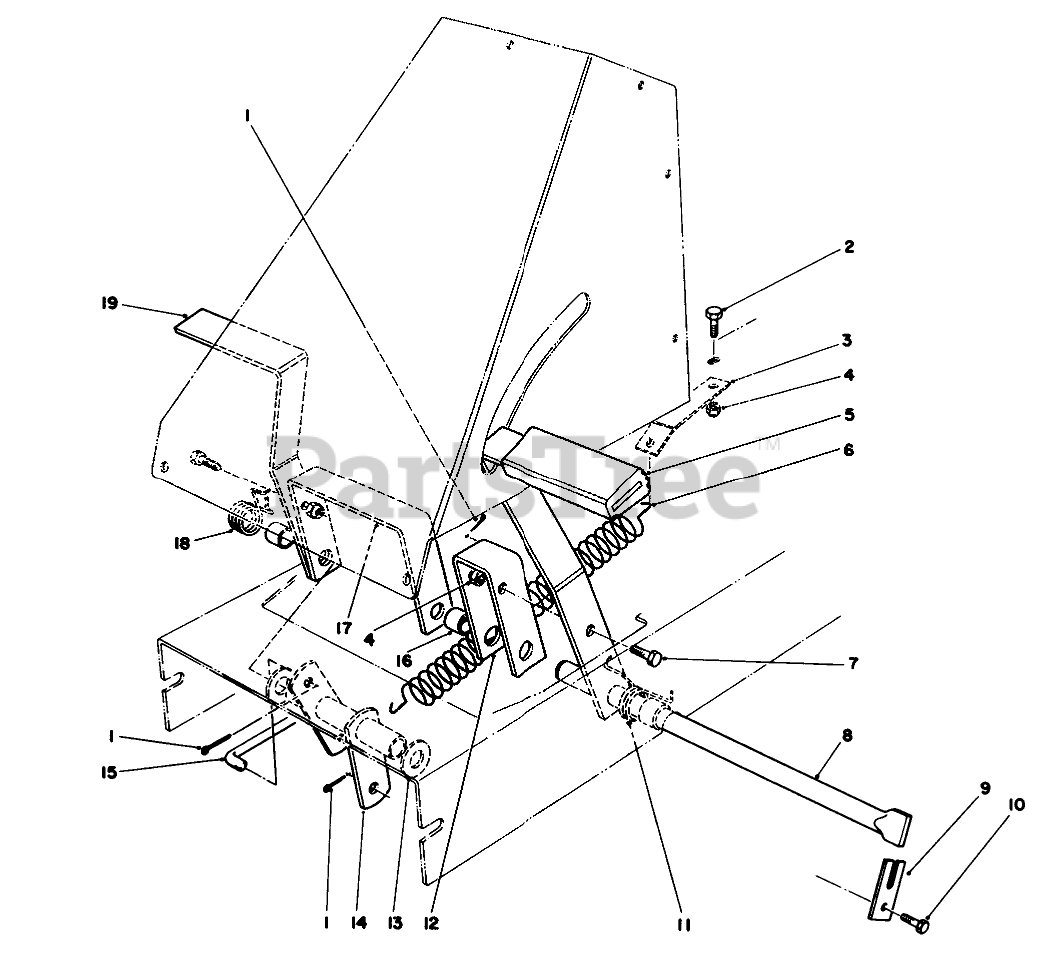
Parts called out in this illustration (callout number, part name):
1	PIN-COTTER
2	SCREW-HH
3	BRKT-SPRING RET
4	NUT-LOCK, NI
5	PAD-PEDAL
6	SPRING-EXTENSION
7	SCREW-HH
8	SHAFT-PEDAL PIVOT
9	RETAINER-SHAFT
10	SCREW-HH
11	SPRING-TORS CLUTCH
12	Bracket-Clutch Pedal
13	WASHER-FLAT
14	Pivot Tube
15	ROD-ENGAGE
16	SPACER-PEDAL
17	Bracket-Brake Pedal
18	SPRING-TORS BRAKE
19	Pedal
